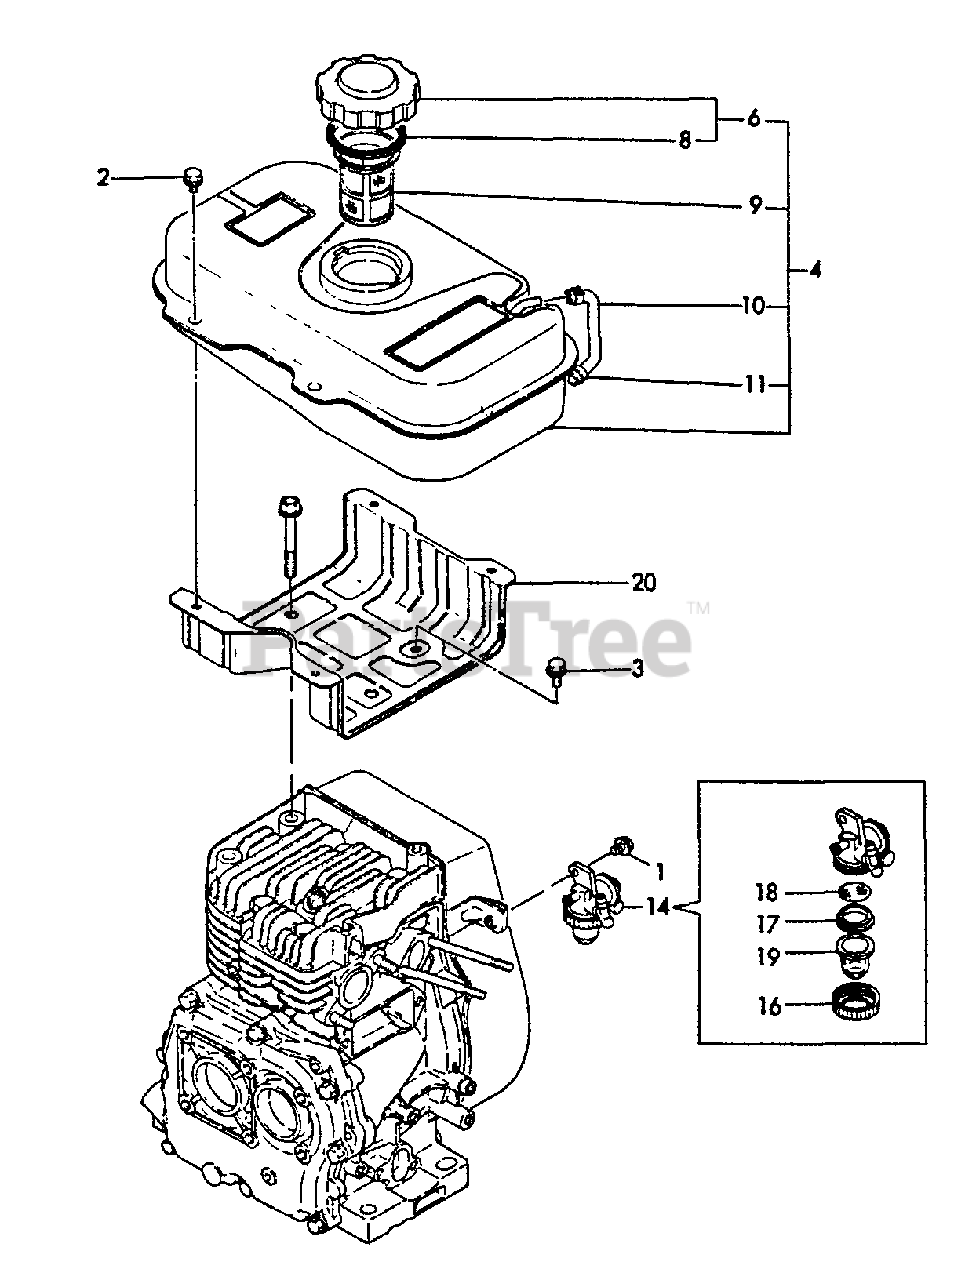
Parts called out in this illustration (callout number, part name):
1	BOLT - 6X8 -- PLATED
2	BOLT - 6X10 -- PLATED
3	BOLT - 6X8 -- PLATED
4	FUEL TANK ASSY
6	CAP ASSY
8	GASKET
9	STRAINER, FUEL
10	PIPE, GAUGE
11	CLAMP, HOSE - 9
14	FUEL COCK ASSY
16	RETAINER
17	GASKET
18	STRAINER, FUEL
19	BOWL, STRAINER
20	BRACKET, FUEL TANK
